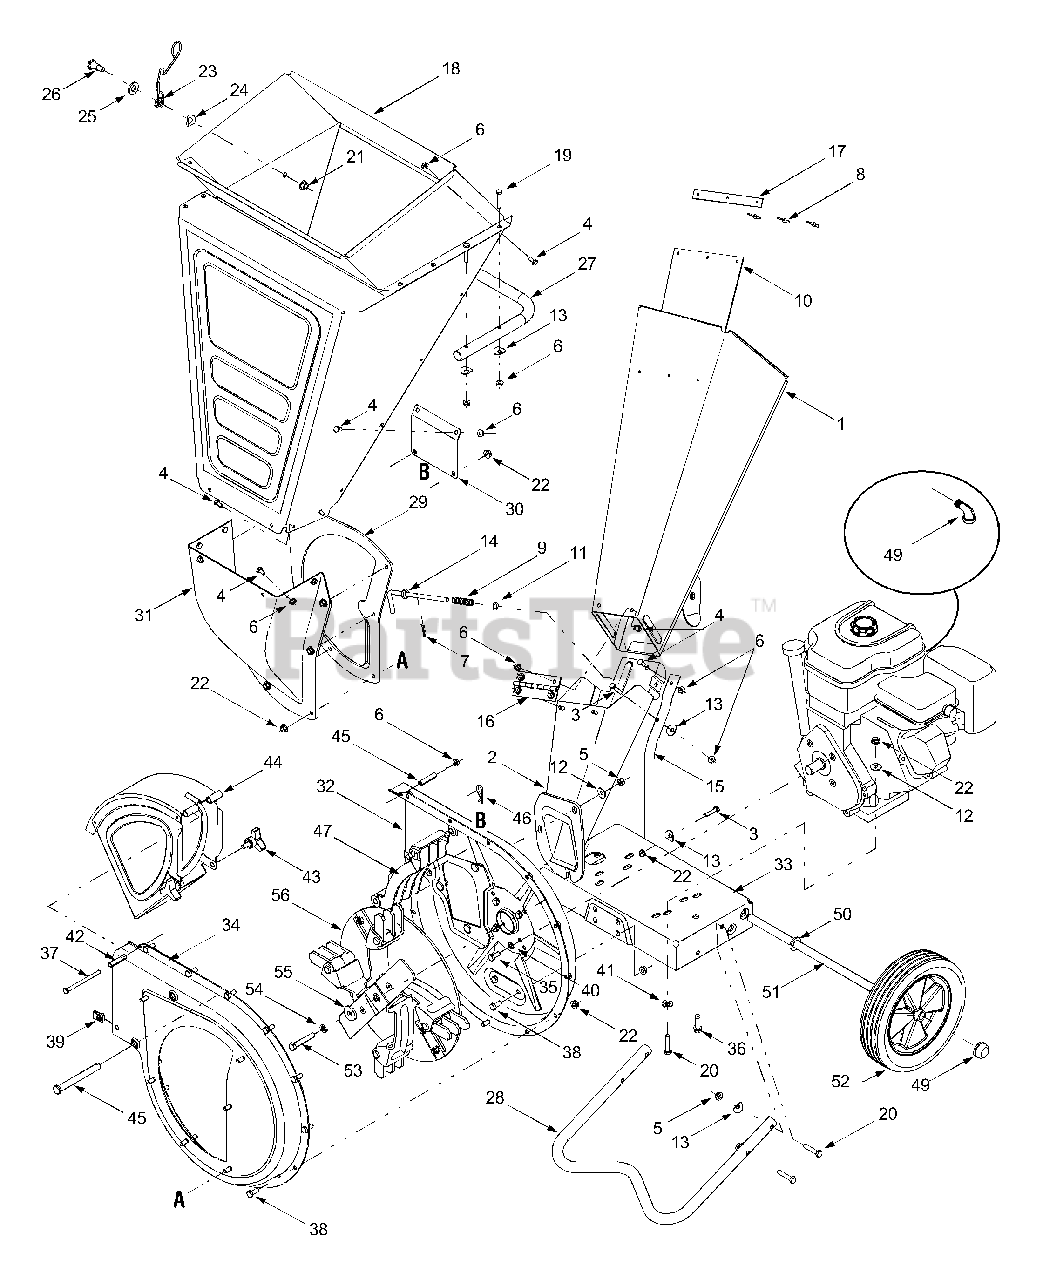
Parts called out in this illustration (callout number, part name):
3	Hex Cap Screw, 1/4-20 x 1.25
4	Hex Cap Screw, 1/4-20 x .5
5	Hex Nut, 5/16-18
6	Hex Lock Nut 1/4-20
7	Cotter Pin
8	Pop Rivet
9	Compression Spring, .531 x 1.75
10	Chute Flap
11	Flat Washer
12	Bell Washer.340 ID x.872 OD
13	Washer,.320 ID x.93 OD
14	Lock Rod
16	Chipper Chute Hinge
17	Chute Flap Strip
20	Hex Cap Screw, 5/16-18 x 1.50
21	Flange Lock Nut, 3/8-16
22	Flange Lock Nut, 5/16-18
23	Torsion Spring
24	Spring Washer, .50 x 1.0 x .022
25	Flat Washer, .50 x 1.0 x .0125
26	Shoulder Screw, 3/8-16, .50 x .685
35	Hex Cap Screw, 5/16-24 x .75
36	Hex Sems Screw, 3/8-16 x 1.25
37	Hex Cap Screw, 1/4-20 x 3.75
38	Hex Cap Screw, 5/16-18 x.75
39	U-Nut, 5/16-18
40	Lock Washer, 5/16
41	Special Lock Washer, 5/16
42	Hinge Spacer, .265 x .380 x 1.66
43	Knob, 5/16-18
45	Clevis Pin, .50 x 4.62
46	Internal Cotter Pin
47	Shredder Screen
48	Push Cap, 5/8
49	Oil Drain Tube
50	Flat Washer, .625 x 1.0
51	Axle, 21.21"
52	Wheel, 10 x 2.5
53	Hex Cap Screw, 3/8-24 x 2.25
54	Lock Washer, 3/8
55	Flat Washer, .406 x 1.25
56	Impeller Assembly
